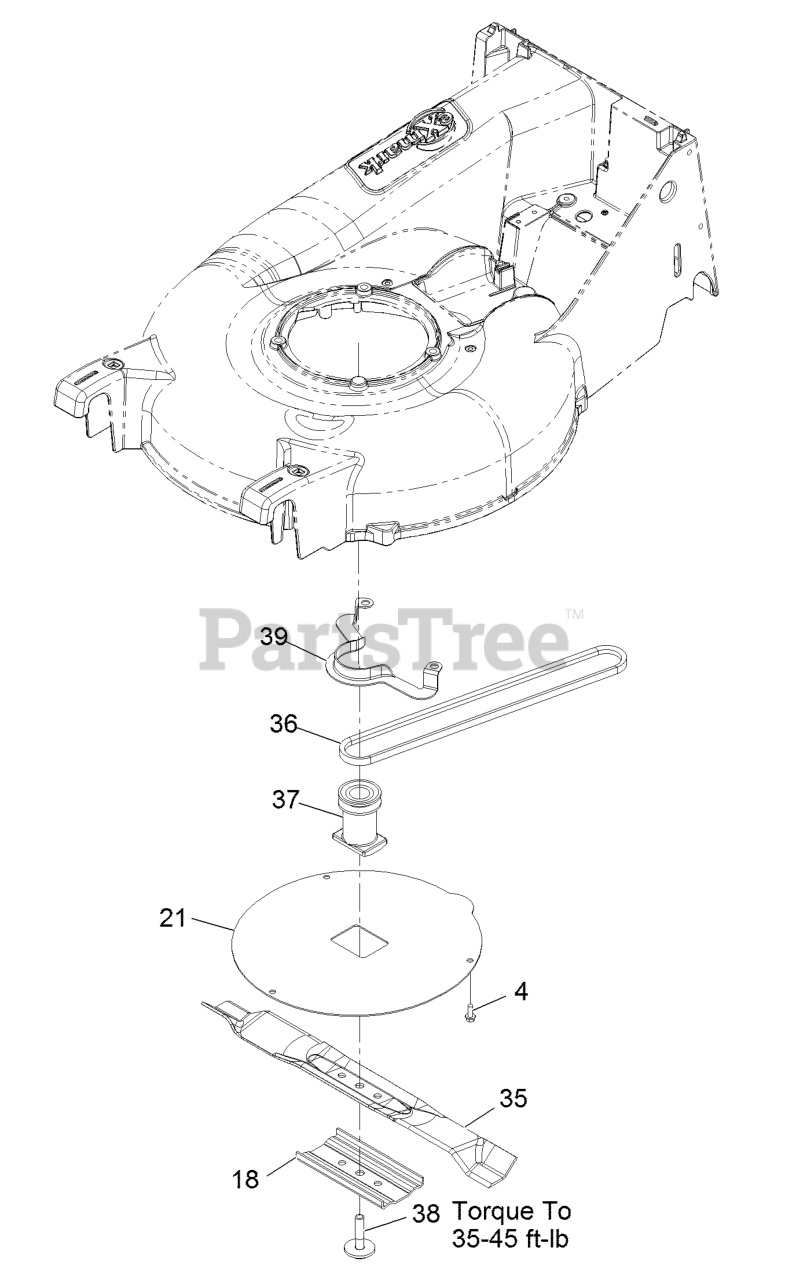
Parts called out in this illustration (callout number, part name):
4	SCREW-HWH
18	SUPPORT-BLADE
36	BELT,3L P21 DRIVE
37	BLADE-ADAPTER
38	BOLT-BLADE, SEM
39	GUIDE-BELT
